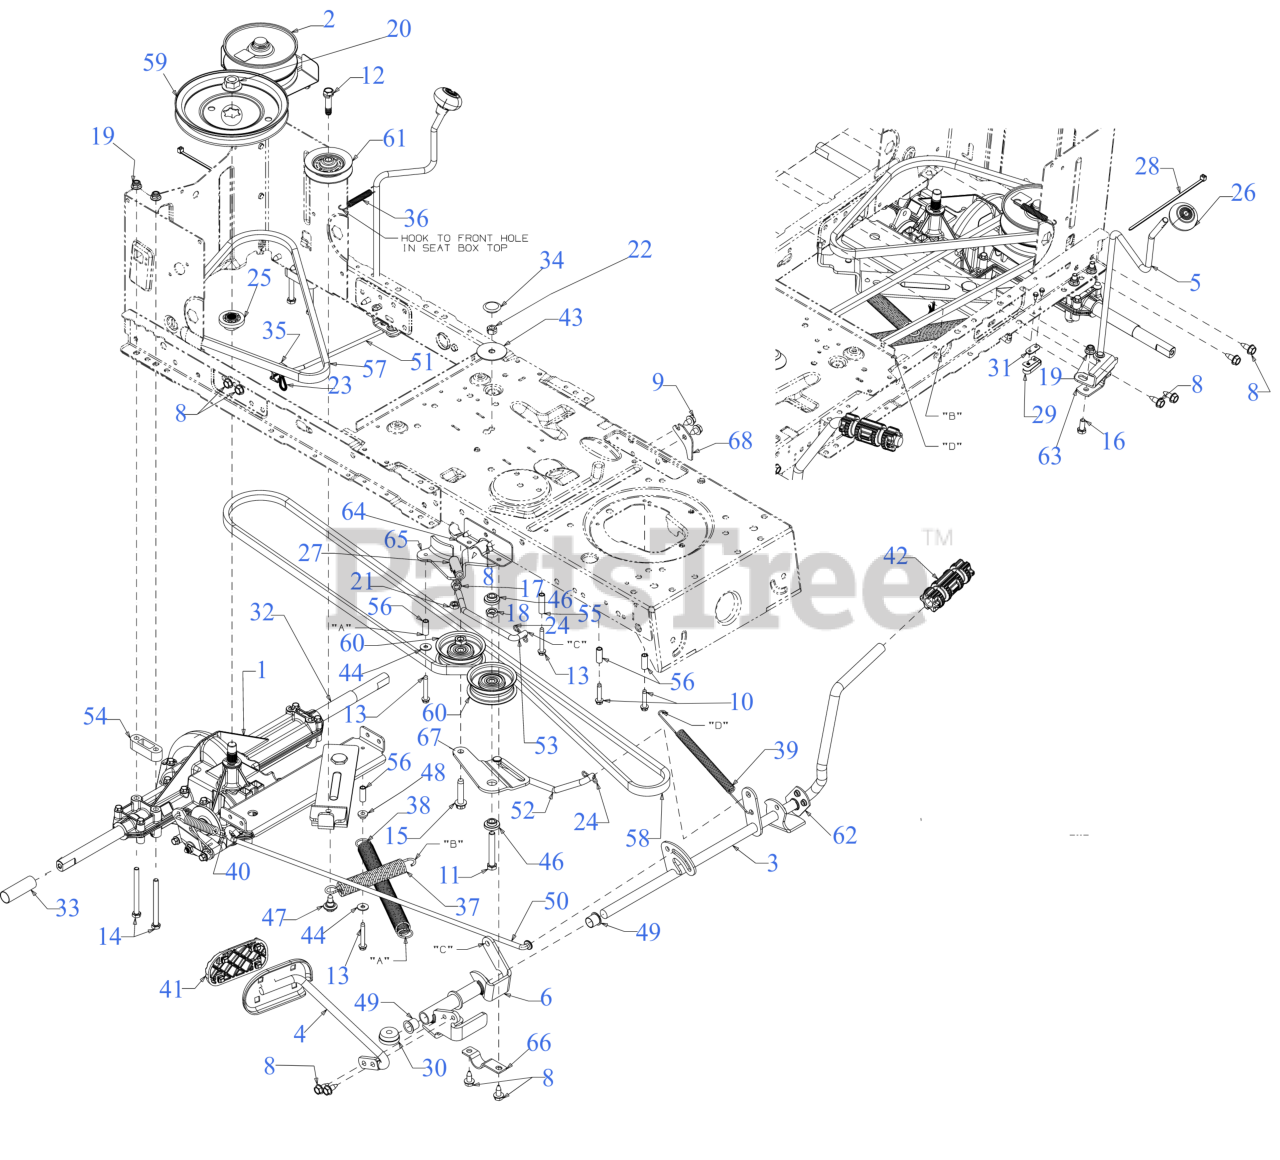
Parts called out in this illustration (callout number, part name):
1	TRANSAXLE
2	Not Serviceable/ Components Only
3	PEDAL ASSEMBLY
5	SHIFT LEVER ASSEMBLY
6	BRACKET ASSEMBLY
7	HEX SCREW WASHER HD #8-18 x 0.500
8	SCREW 5/16-18 x .750
9	SCREW 5/16-18 x .625
10	SCREW 1/4-20 x 1.25
11	HEX SCREW-3/8-16X2.5 GR5
12	SCREW 3/8-16 x 1.500
13	SCREW 1/4-20 x 1.750
14	SCREW 5/16-18 x 3.50 GR5
14	SCREW 5/16-18X3.5 GR5
15	SCREW 3/8-16 x 1.75
16	SCREW 5/16-18 x .75 GR5
17	HEX NUT
17	HEX NUT 3/8-24
18	JAM NUT 7/16-20
19	FLANGE LOCK NUT 5/16-18
20	FLANGE NUT W/HUB
21	HEX JAM NUT 3/8X24
21	HEX NUT 3/8-24
22	LOCK NUT 3/8-16
23	COTTER PIN
24	BOW TIE COTTER PIN 1/4-5/16
25	PULLEY HUB
26	SHIFT KNOB
27	BALL JOINT
28	7" CABLE TIE
29	SAFETY SPRING SWITCH
31	INSULATOR NUT PLATE
34	DECK HOLE PLUG
35	SHIFT ROD BEARING
36	EXTENSION SPRING .38 OD x 3.25 LG
37	EXTENSION SPRING .97 x 6.18
38	EXTENSION SPRING 1.00 x 11.125 x .095
39	EXTENSION SPRING .562 OD x 10.5
40	EXTENSION SPRING
42	BRAKE PEDAL PAD
43	HUB CAP WASHER .406 x 1.92 x .060
44	FLAT WASHER
46	SHOULDER SPACER 1.00 x .38 x .38
47	SHOULDER SCREW .43X.29X5/16-18 TT
48	SHOULDER SPACER
49	NYLINER BEARING
52	TRANSMISSION FOOT PEDAL ROD
53	IDLER ADJUSTMENT ROD
54	TRANSAXLE SPACER
55	SPACER:.260 x .372 x 1.420
57	V-BELT 5L x 40.75
58	V-BELT 5L-90.93
59	V-PULLEY W/HUB 7.25 DIA
60	FLAT IDLER PULLEY 2.75 OD
61	V-IDLER PULLEY A x 3.06 OD
63	SHIFT ADJUSTMENT BRACKET
64	PEDAL FRAME BRACKET (RH)
65	DOULE IDLER BRACKET
66	SUPPORT BRACKET
67	IDLER BRACKET
68	PEDAL STOP PLATE
